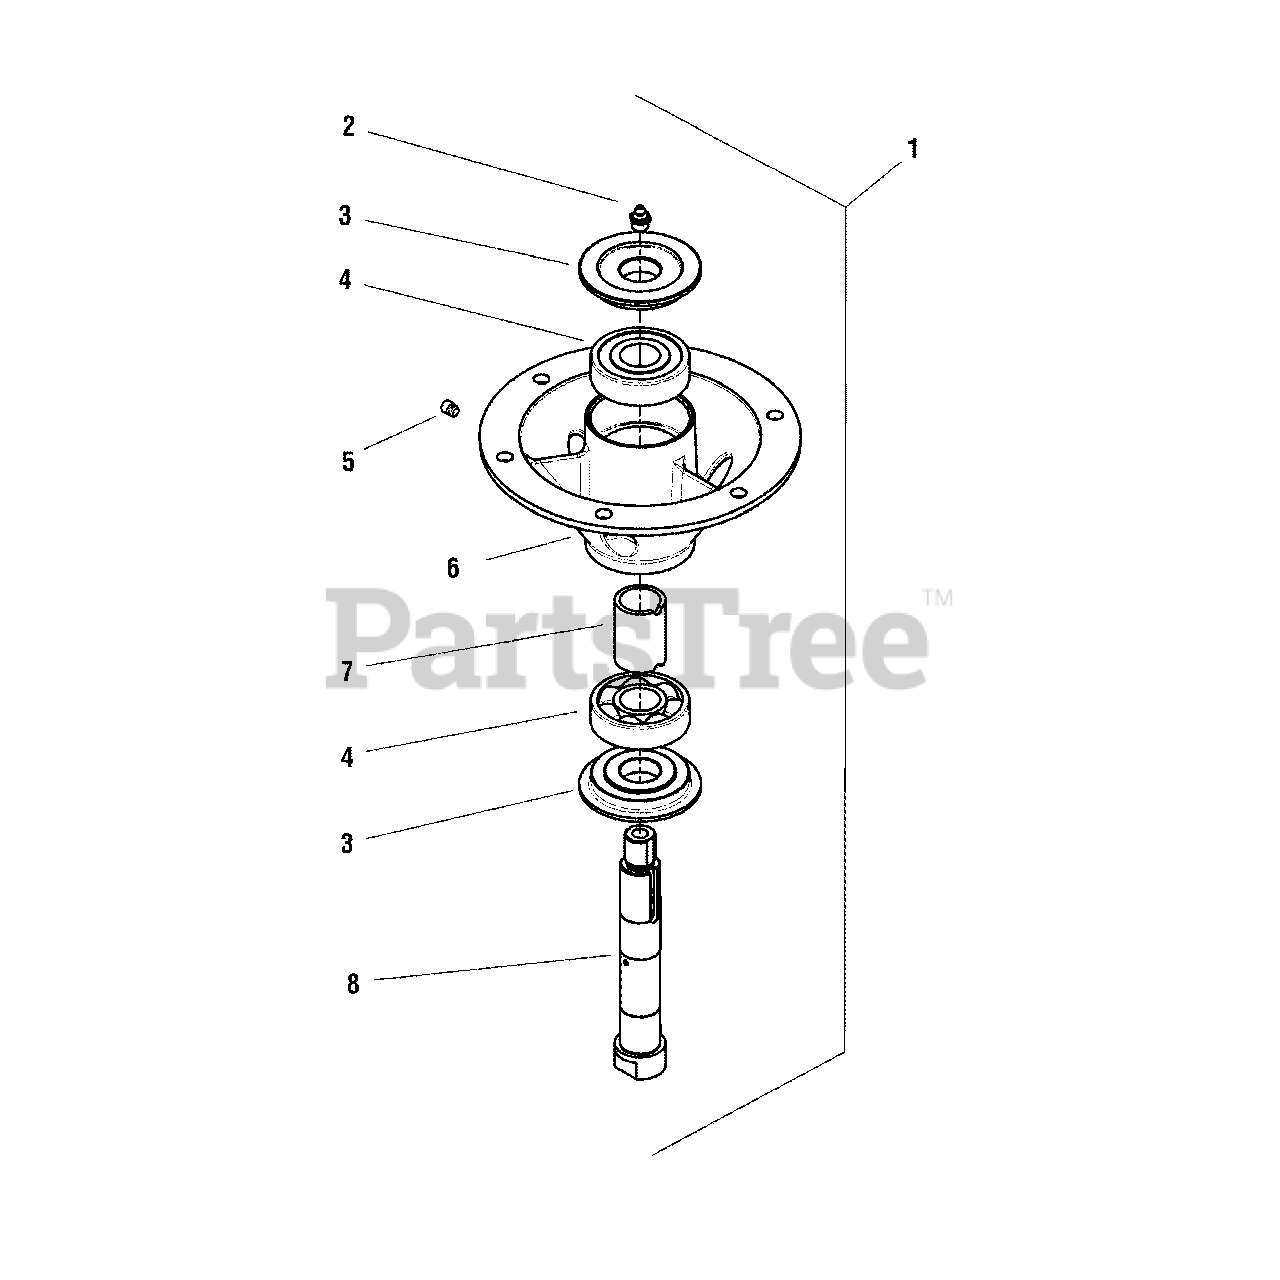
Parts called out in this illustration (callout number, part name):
1	SPINDLE ASSEMBLY, CAST IRON, COMPLETE
2	GREASE FITTING
3	TRASH SHIELD
4	RELIEF VALVE
5	BEARING
6	HOUSING, SPINDLE, BOTTOM MOUNT
7	SPACER, 1.00 X 1.25 X 1.75
8	SPINDLE SHAFT
